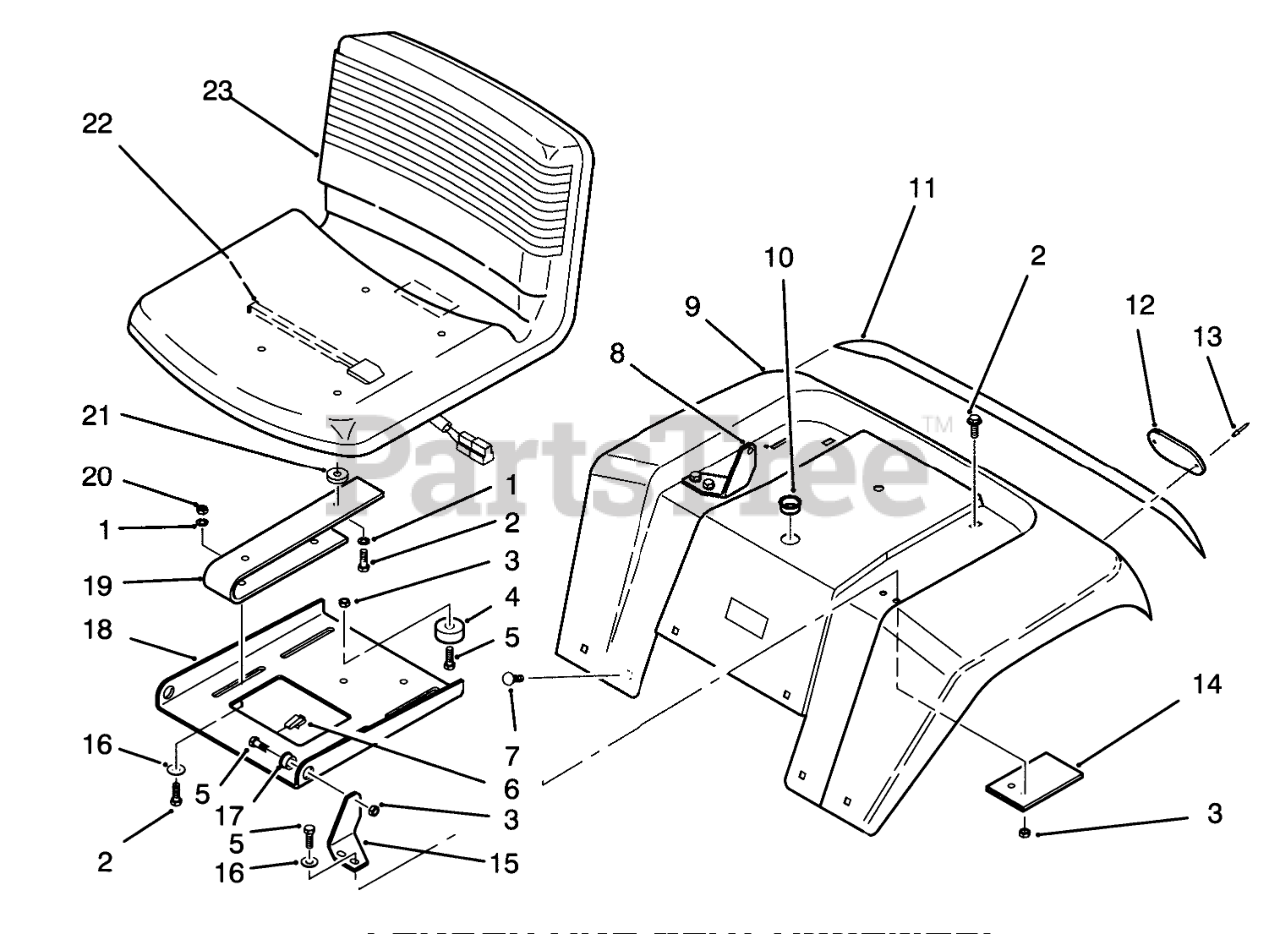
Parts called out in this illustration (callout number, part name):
1	WASHER-LOCK
2	SCREW-HH
3	Nut
4	BUMPER SJ5514 BLACK
5	SCREW-HH
6	J-CLIP
7	NUT-HEX, JAM
8	Bracket-Pivot RH
9	FENDER R
10	BUSHING-NYLON 1.093
11	DECAL-FENDER
12	Reflector
13	Poprivet
14	PLATE R
15	BRACKET-PIVOT L.H B
16	WASHER-PLAIN
17	BUSHING
18	PLATE-SEAT PIVOT B
19	SPRING-SEAT B
20	NUT-HEX
21	SPACER-NYLON
22	SWITCH-SEAT
23	SEAT V-510
